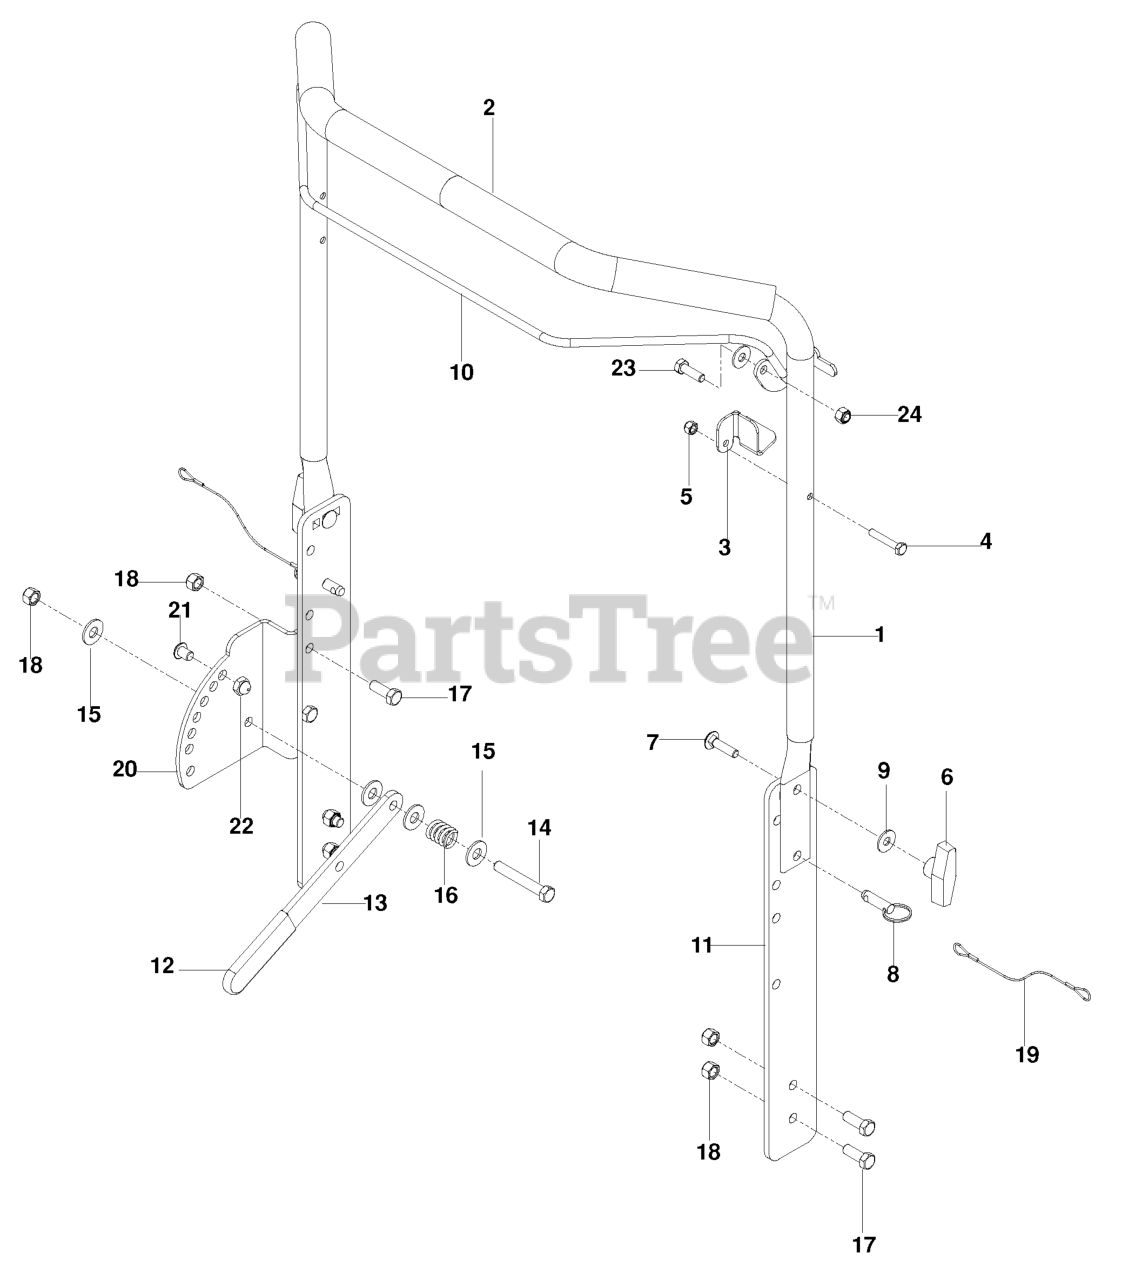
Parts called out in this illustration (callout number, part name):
1	HANDLE GRAY
3	CABLE TAB POWER RAKE
4	SCW 1/4-20 X 1-1/2 HEX
5	NUT.1/4-20.HEX.NYLOC.ZD
7	BOLT, CARRIAGE 5/16X1-1/4
8	DETENT PIN RAKE/DT
9	WASHER 5/16 FLAT
10	BAIL - ORANGE
11	HANDLE SIDE GRAY
13	LEVER, PLATED
14	HCS 3/8C X 2
15	WASHER 3/8 FLAT
16	COMPRESSION SPRING
17	HCS 3/8-16X1.GRD.5.ZD
18	NUT 3/8-16 NYLOC
20	HEIGHT ADJUSTMENT PLATE
21	BLT 3/8-16 X 1/2 BTN HD BLK SP
22	NUT 3/8-16 ACORN HEX
23	HCS 5/16C X 1
24	NUT 5/16 NYLOC
